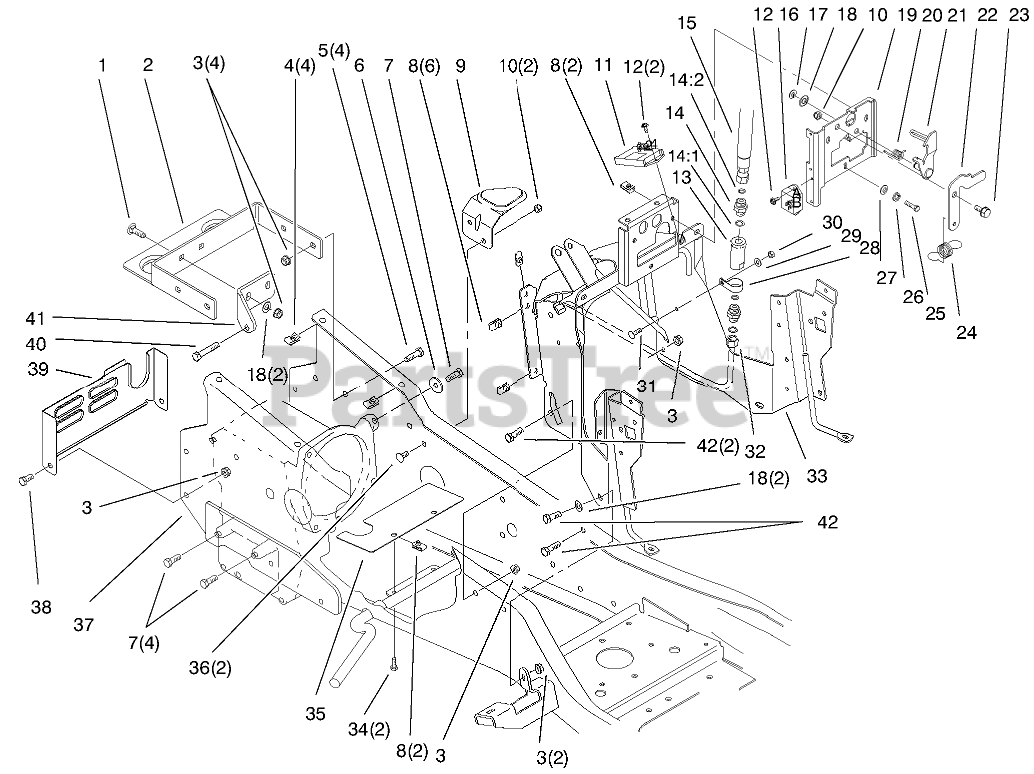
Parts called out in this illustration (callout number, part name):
1	BOLT-CARR
2	Support-Gas Tank
3	NUT-LOCK, NI
4	NUT-U
5	SCREW-HH
6	WASHER
7	SCREW-HH, LOCK
9	SUPPORT-TANK, FUEL
10	NUT-LOCK, NI
11	MODULE - DIESEL
12	SCREW
13	FILTER-SCREEN, HYD
14	FITTING-HYD. STRAIGHT
14:1	O-RING
14:2	O-RING
15	HOSE ASM
16	MODULE - CRUISE
17	RING-RETAINING
18	WASHER-FLAT
19	BRACKET-LATCH
20	SPRING-LEVER, LATCH
21	LEVER-LATCH
22	LATCH-LEVER, TENSION
23	BOLT-SHOULDER
24	SPRING-LEVER, LATCH
25	SCREW-HH
26	WASHER-LOCK
27	WASHER-FLAT
28	CLAMP-R
29	WASHER-FLAT
30	NUT-LOCK, NI
31	BOLT-CARR
32	TUBE-HYD
33	WA-TOWER
34	SCREW-HH
35	BAFFLE-FAN
36	BOLT-CARR
37	Frame
38	SCREW-HH
39	COVER-REAR
40	SCREW-HH W/LOCTITE
41	Strap-Torque
42	SCREW-HH
